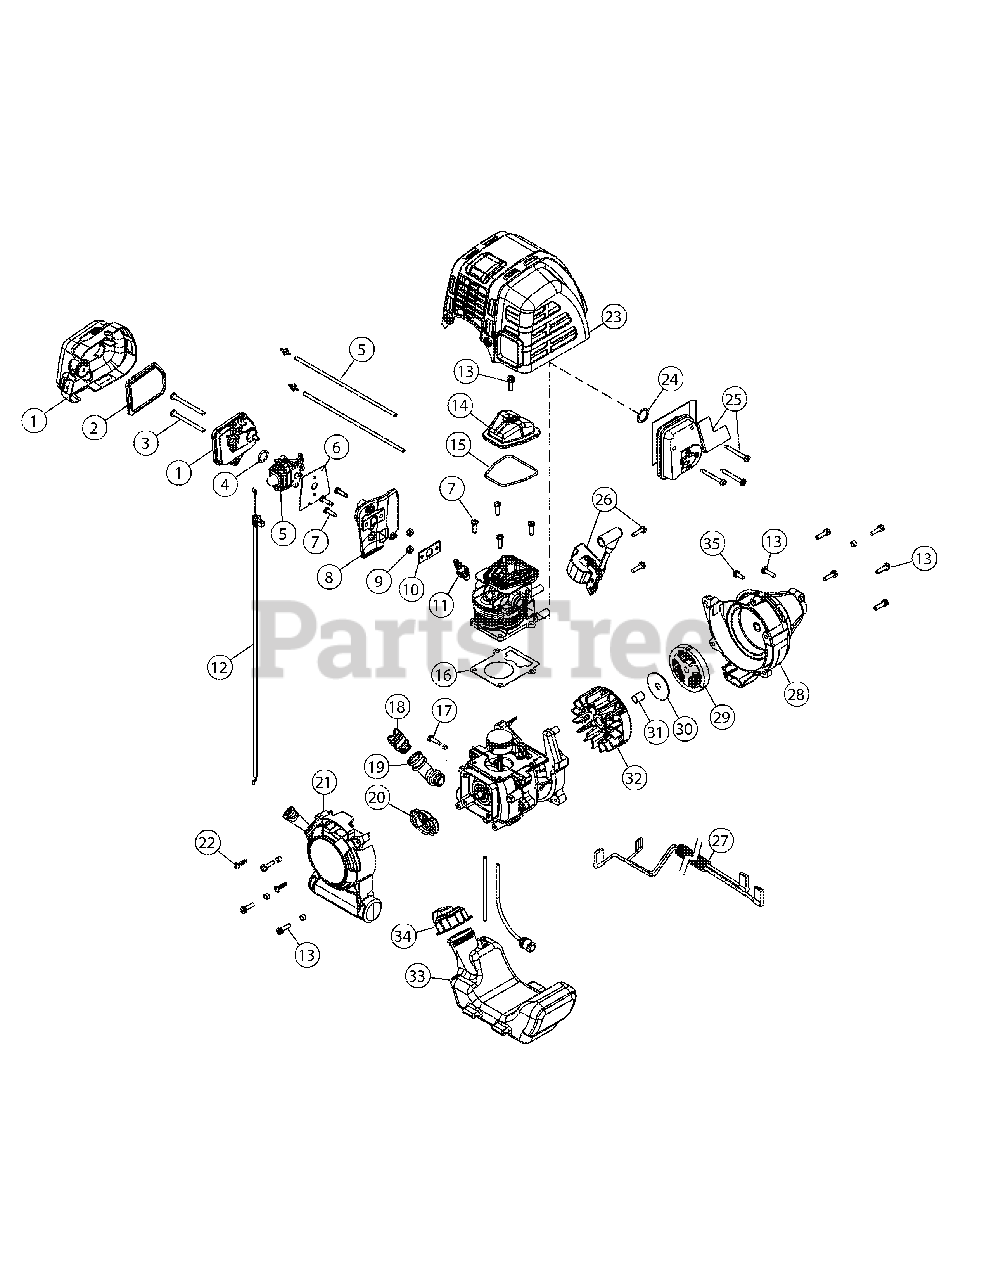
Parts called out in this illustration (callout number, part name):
1	Air Cleaner Assembly
2	Air Filter
3	Screw
4	Carburetor O-Ring
5	Carburetor Assembly w/ Fuel Lines
6	Carburetor Gasket
7	Screw
8	Insulator
9	Nut
10	Insulator Gasket
11	Spark Plug
12	Throttle Cable
13	Screw
14	Valve Cover
15	Valve O-Ring
16	Cylinder Gasket
17	Screw
18	Oil Plug Assembly
19	Oil fill Tube Assembly
20	Pawl Assembly
21	Rear Starter Cover Assembly
22	Screw
23	Starter Housing
24	Muffler Gasket
25	Muffler Assembly
26	Module Assembly
27	Lead Wires
28	Clutch Cover Assembly
29	Clutch
30	Clutch Washer
31	Spacer
32	Flywheel
33	Fuel Tank
34	Fuel Cap
35	Anti-Rotation Screw
